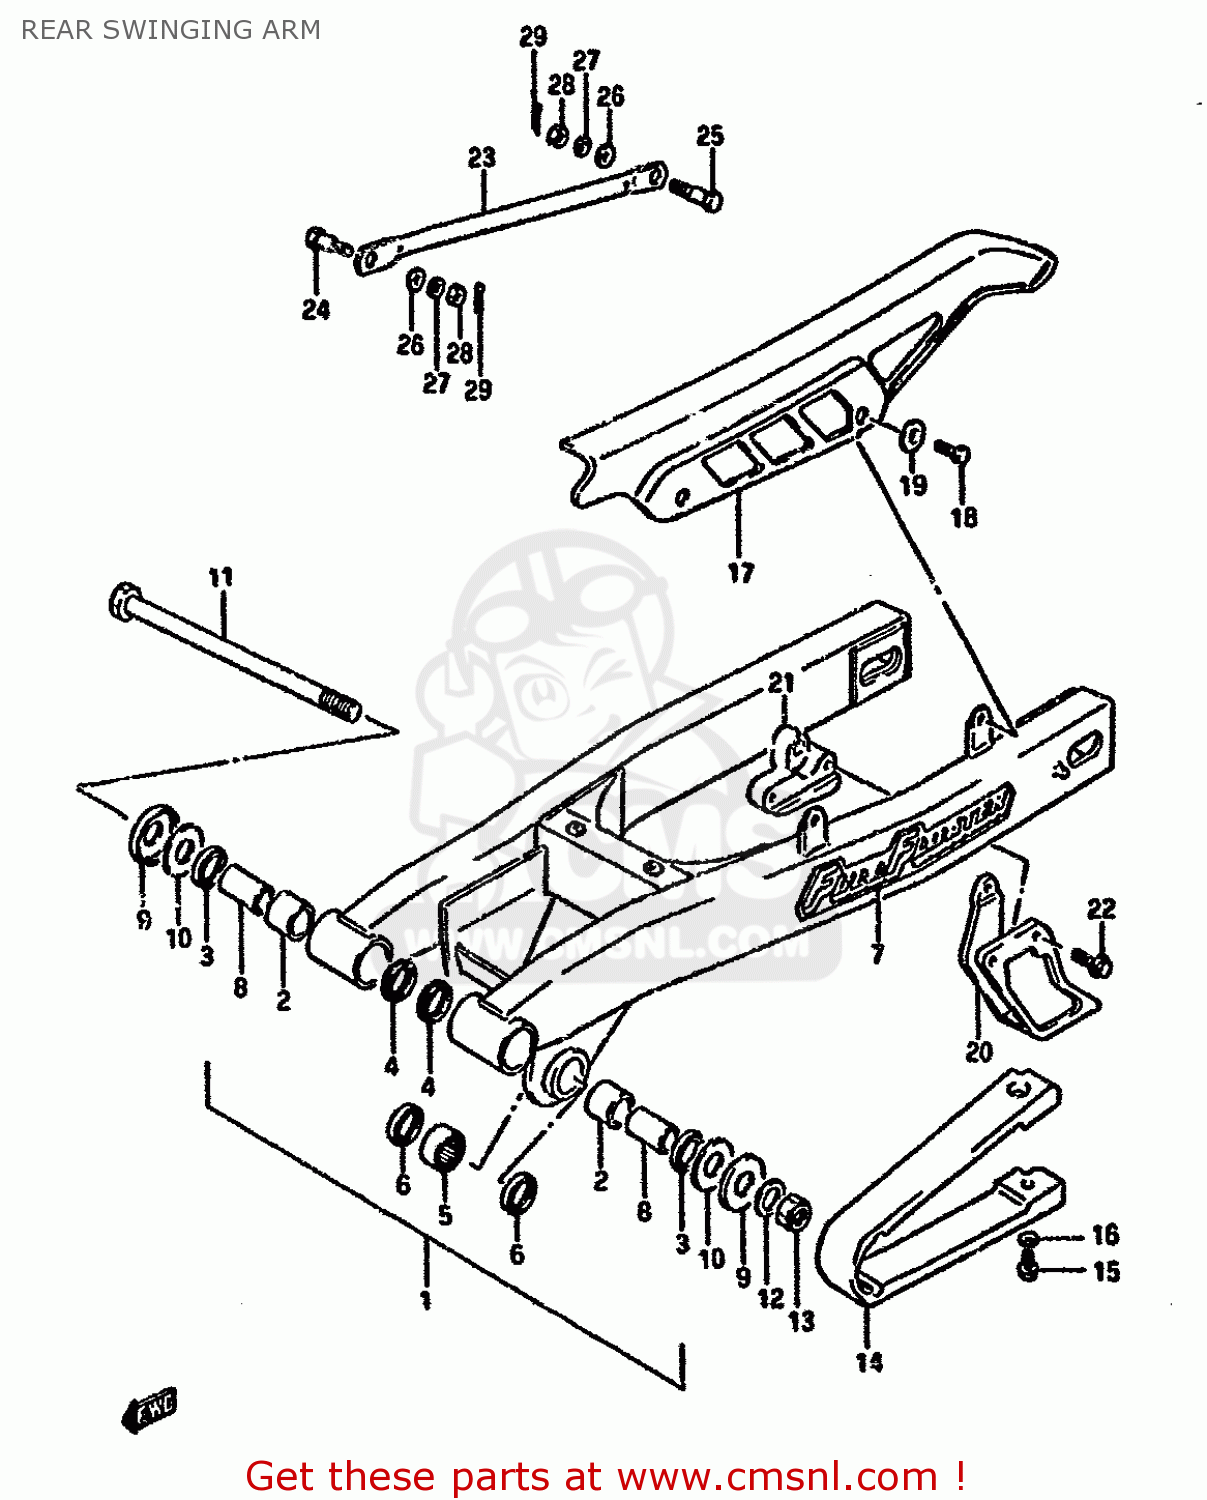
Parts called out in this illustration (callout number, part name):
1	SWING ARM ASSEMBLY,REAR
2	BUSHING,RR SWGARM PIVOT
3	OIL SEAL
4	SEAL,OIL(20X27X5)
5	BEARING
6	SEAL,CUSHION LEVER OUT DUST
7	EMBLEM
8	SPACER,RR SWGARM PVT
9	COVER,RR SWGARM DUST SEAL
10	WASHER
11	SHAFT,REAR SWING ARM
12	WASHER
13	NUT
14	BUFFER,CHAIN TOUCH DEFENSE
15	BOLT
16	WASHER
17	CASE,CHAIN
18	BOLT
19	WASHER
20	GUIDE,CHAIN
21	RUBBER,CHAIN GUIDE
22	BOLT
23	TORQUE LINK,RR
24	BOLT(8X22)
25	BOLT(8X26.5)
26	WASHER
27	LOCK WASHER
28	NUT
29	PIN 20X20
